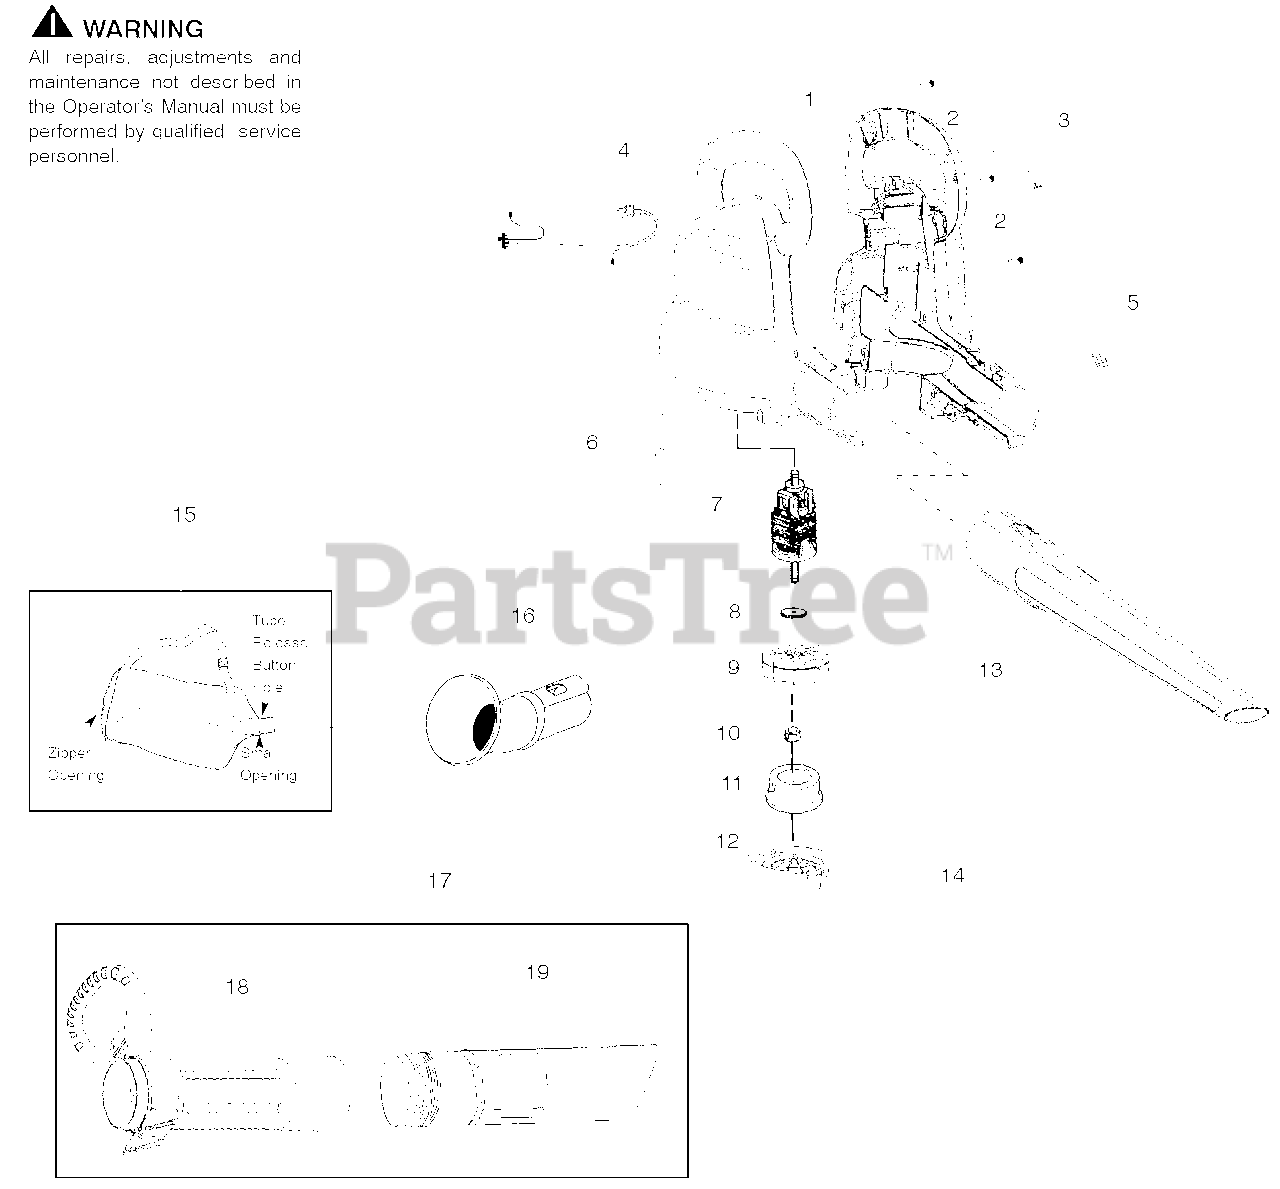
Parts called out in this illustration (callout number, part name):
1	Housing Set
3	Cover - Switch
4	Assy. Wiring Harness
5	Button - Tube Latch
6	Button - Door Latch
7	Assy. Motor
9	Impeller
10	Nut - Impeller
11	Restrictor - Inlet
12	Door - Vacuum Inlet
13	Tube - Blower
14	Spring - Door
15	Assy. - Vac Bag
16	Attachment-Vac Bag
17	Kit-Upper/Lower Tube w/handle
18	Tube - Upper Vac w/handle
19	Tube - Inlet Vacuum
